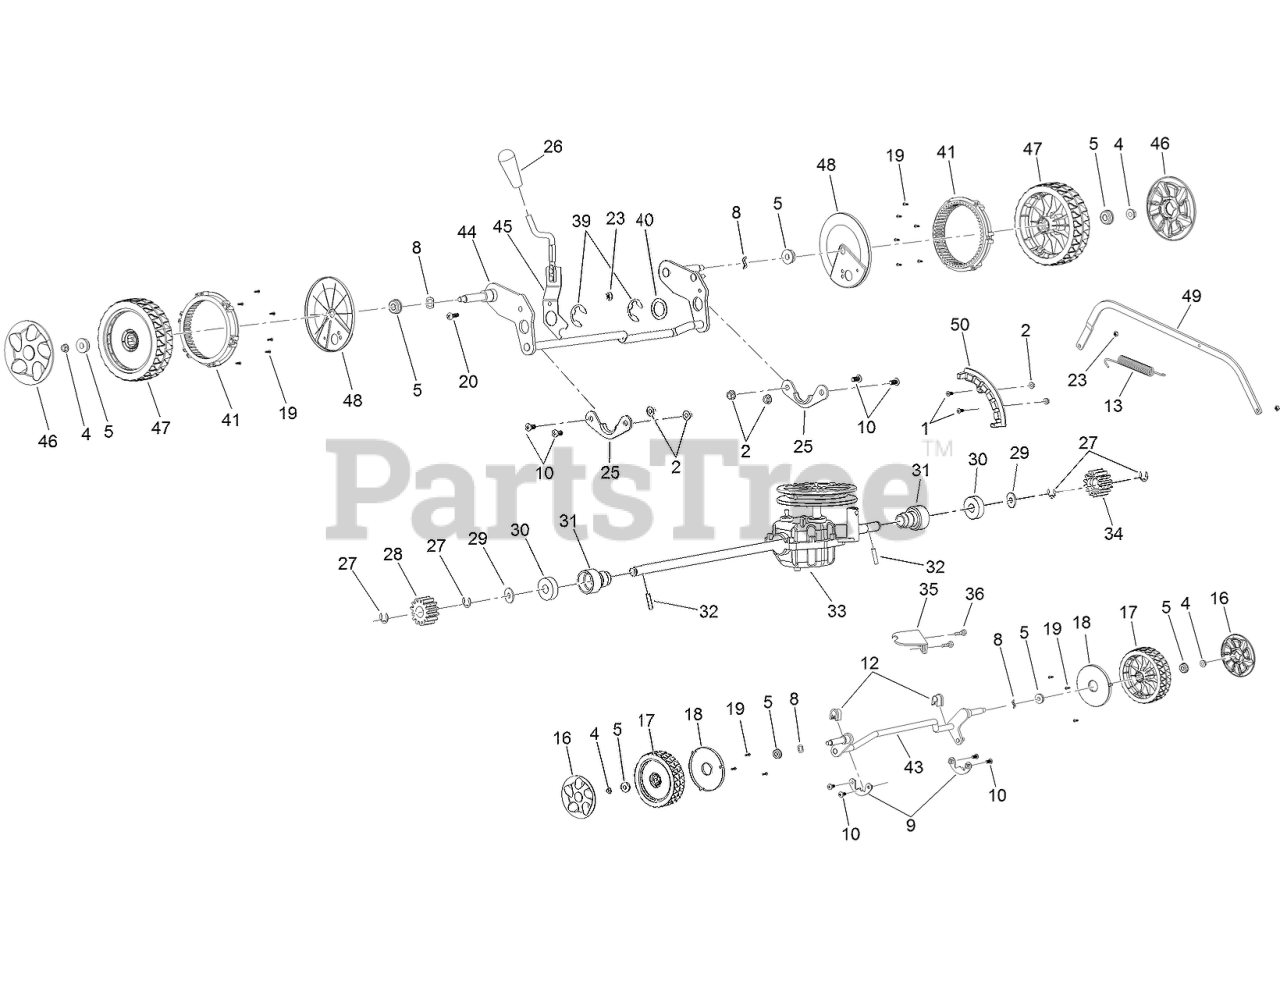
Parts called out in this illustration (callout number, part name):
1	SCREW-TOOTH
2	NUT-LOCK, FLANGE
4	NUT-LOCK, FLANGE
5	BEARING
8	WASHER-WAVE
9	CLAMP-AXLE, FIXED
10	SCREW-TOOTH
12	RING-FIXED
13	SPRING-TENSION
16	CAP-HUB (8)
17	WHEEL ASM (8)
18	COVER-WHEEL, DUSTPROOF
19	SCREW-SELF DRIVING
20	SCREW-PAN, CROSS
23	NUT-LOCK
25	RING-FIXED
26	HANDLE-LEVER, HOC
27	WASHER-SPRING
28	GEAR OUTPUT ASM-RH
29	WASHER-FLAT
30	BEARING
31	SHEATH-BEARING
32	PIN-CYNLINDRICAL
33	GEARBOX
34	GEAR OUTPUT ASM-LH
35	BRACKET-LOCATION
36	BOLT-HH, FLANGE
39	WASHER-SPRING
40	WASHER
41	RING-GEAR
43	FRONT WHEEL AXIS ASM
44	REAR AXLE SHAFT ASM
45	HANDLE ASM
46	CAP-HUB (11)
47	WHEEL ASM (11)
48	COVER-WHEEL, DUSTPROOF (11)
49	BRACKET-CONNECTING, HOC
50	BOARD-ADJUSTER, HOC
